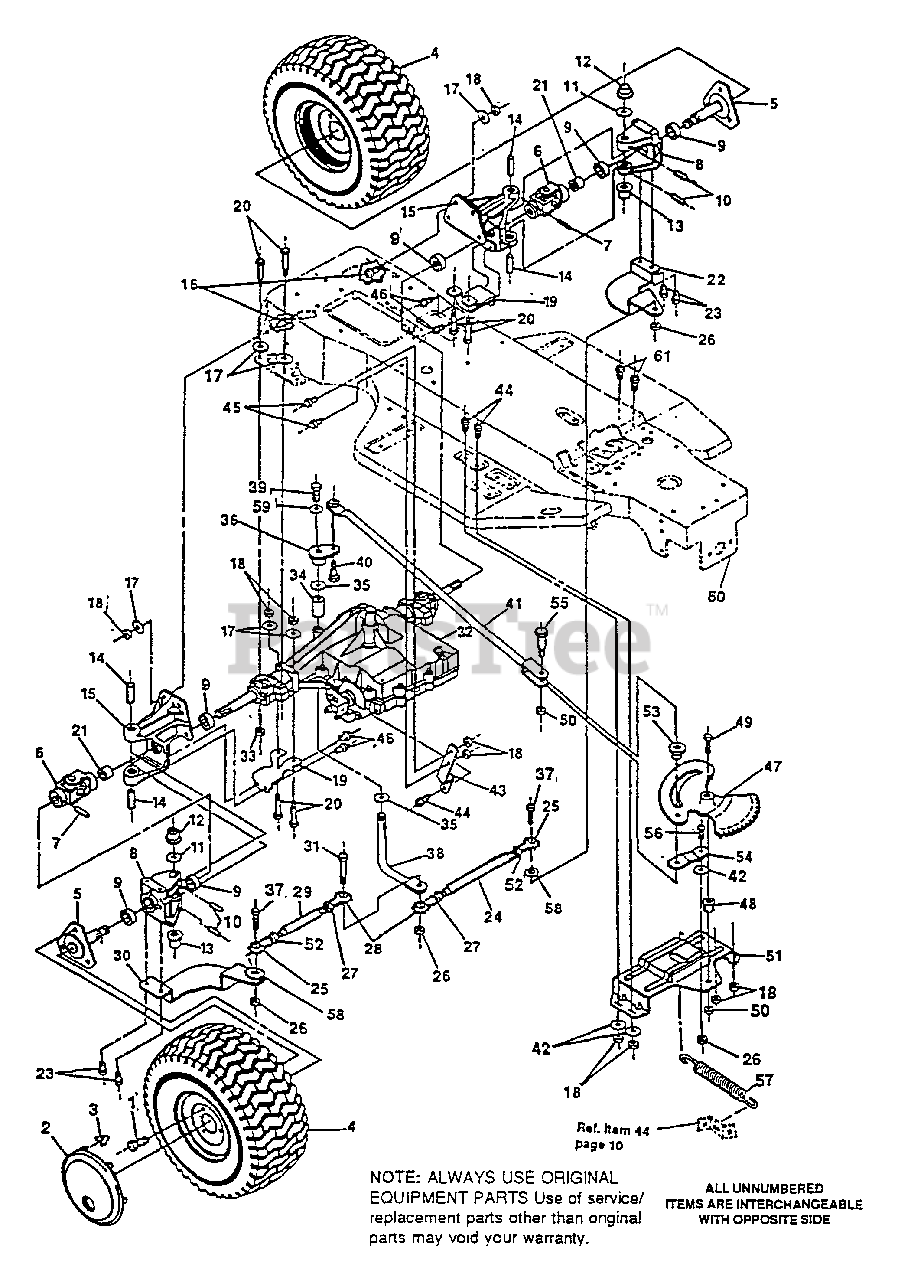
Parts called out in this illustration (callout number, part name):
1	Screw, Hx Hd, 1/2-20 x 1/2 In.
2	Hubcap, 8 In.
3	Clip, Hubcap
4	Wheel & Tire Assembly, Rear
4	Tire, 20x10.0x8, Turf
4	Valve Stem
5	Hub Assembly
6	U-Joint Assembly
7	Pin, Grooved, 1/4 x 1-1/2 In.
8	Bracket Assembly, Steering Pivot, Outer
9	Bearing
10	Pin, Spring, 1/4 x 1-1/2 In.
11	Washer, Flat
12	Bushing, Shouldered
13	Bushing, Shouldered
14	Pin, Steering Hinge
15	Bracket Assembly, Steering Pivot, Inner
16	Screw, Hx Hd, 5/16-18 x 1 In.
17	Washer, Flat, 11/32 In.
18	Nut, Hx, Ctrlk 5/16-18 Thd.
19	Bracket, Transaxle Mounting
20	Screw, Hx Hd, 5/16-18 x 2-1/4 In.
22	Arm, Rear Wheel Steer, L.H.
23	Screw, Self-Tap, 3/8-16 x 3/4 In.
24	Tie Rod, L.H. (1/2"x9-1/2")
25	Tie Rod-End, L.H.
26	Nut, Hex, Ctrlk, 3/8-24 Thd.
27	Nut, Hex, Jam, 3/8-24 Thd.
28	Tie Rod End, R.H.
29	Tie Rod, 1/2 x 8" Long
30	Arm, Rear Wheel Steer, R.H.
31	Screw, Hx Hd, 3/8-24 x 1-3/4 In.
32	Transaxle
33	Nut, Hx, Wd Fl, Lk 5/16-18 Thd.
35	Washer, Flat, 49/64 In.
36	Steering Pivot
37	Screw, 3/8-24 x 1-1/4 In.
38	Shaft, Steering Pivot
39	Screw, 5/16-24 x 1 In.
40	Bolt, Shoulder, 3/8-24 Thd.
41	Rod Assembly, Rear Wheel Steer
42	Washer, Flat, 3/8 In.
43	Bracket, Transaxle Stabilizer
44	Screw, Hx Hd, Self-Tap, 5/16-18 x 3/4 In.
45	Screw, Hx Hd, 5/16-18 x 5/8 In.
46	Screw, Hx Hd, Self-Tap, 5/16-18 x 5/8 In.
47	Assembly, Sector Gear
48	Bushing, Sector Gear
49	Screw, Hx Hd, 1/2-20 x 2-3/8 In.
50	Nut, Hx, Ctrlk, 1/2-20 Thd.
51	Plate, 4-Wheel Steer Pivot
52	Nut, Jam, 3/8-24 Thd.
53	Cam Yoke Roller
54	Arm, Roller Swing
55	Shoulder Bolt, Cam Roller
56	Shoulder Bolt, Cam Follower Arm Pivot
57	Spring, Clutch/Brake Pedal Return
58	Washer, Split Lock
59	Washer, Flat
60	Main Frame
61	Screw, 5/16-18 x 1/2 In. Taptite
